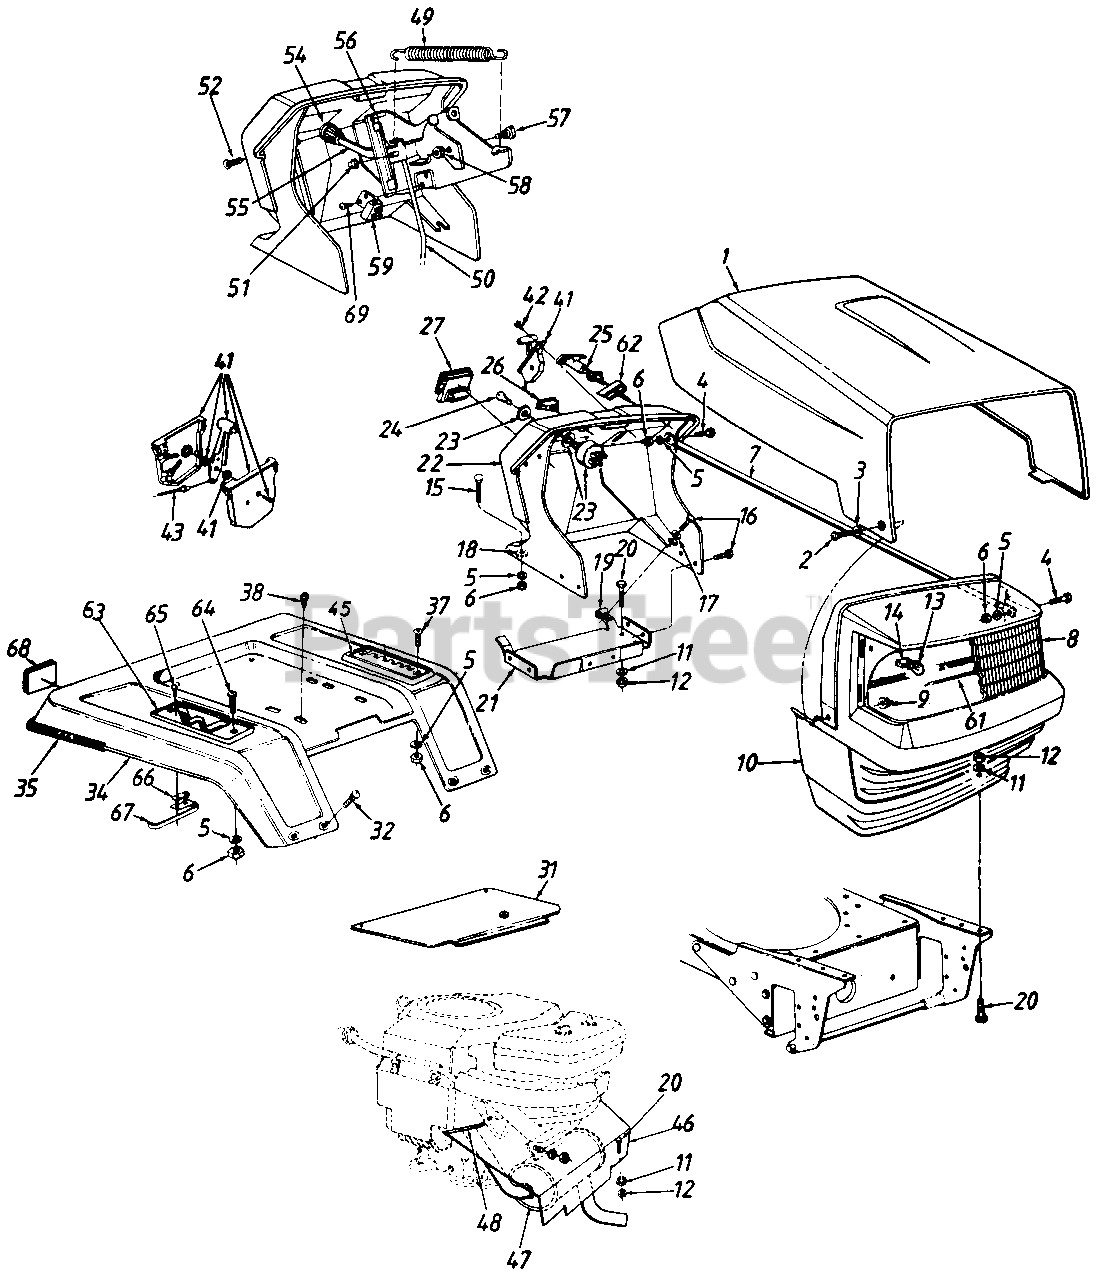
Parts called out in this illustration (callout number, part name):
1	Hood
2	Shld. Bolt .375" Dia. x .125" Lg.
3	Spr. Wash. .265" I.D. x .562" O.D.
4	Hex Bolt 1/4-20 x .62" Lg.
5	L-Wash. 1/4" I.D.
6	Hex Nut 1/4-20 Thd.
9	Flange L-Nut 1/4-28 Thd.
10	Grille
11	L-Wash. 5/16" I.D.
12	Hex Nut 5/16-18 Thd.
13	Lamp
14	Socket
15	Carriage Bolt 1/4-20 x 1.0" Lg.
16	Hex Wash. Hd. TT-Tap Scr. 1/4-20 x .5" Lg.
17	Fl-Wash. .281" I.D. x 73n O.D.
18	Bolt Retainer 1/4" I.D.
19	Speed Nut 1/4-20 Thd.
20	Hex Bolt 5/16-18 x .75" Lg.
23	Ignition Switch
24	Ignition Key
25	Choke Control
26	Light Switch
27	Ammeter
31	Shift Cover
32	Carriage Bolt 1/4-20 x .5" Lg.
37	Truss Mach. Scr. #1/4-20 x 1" Lg.
38	Hex Wash. Hd. AB-Tap Scr. 5/16 x .75" Lg.
41	Throttle Box Ass'y.
42	Truss Mach. AB-Tap Scr. #10 x .5" Lg.
43	Throttle Control Wire
45	Speed Selector Plate
46	Front Heat Shield
47	Muffler
48	Trim Strip 12" Lg.
49	Ext. Spring 5.06" Lg.
50	Deck Control Rod
51	Speed Nut 1/4" Rod
52	Torx Mach. Scr. 1/4 x .62" Lg.
54	PTO Knob
55	PTO Lever
56	PTO Bracket
57	Shld. Bolt .437" Dia. x .162"
58	Hex L-Nut 5/16-18 Thd.
59	Safety Switch
61	Grille Reflector Label
62	Retainer Clip
63	Forward/Reverse Index Brkt.
64	Truss Mach. Scr. 1/4-20 x .75" Lg.
65	Hex Wash. Hd. AB-Tap Scr. #8 x .5" Lg.
66	Insulator Nut Plate
67	Reverse Safety Switch
68	Reflector
69	Hex Wash. Hd. B-Tap Scr. #10 x .38" Lg.
